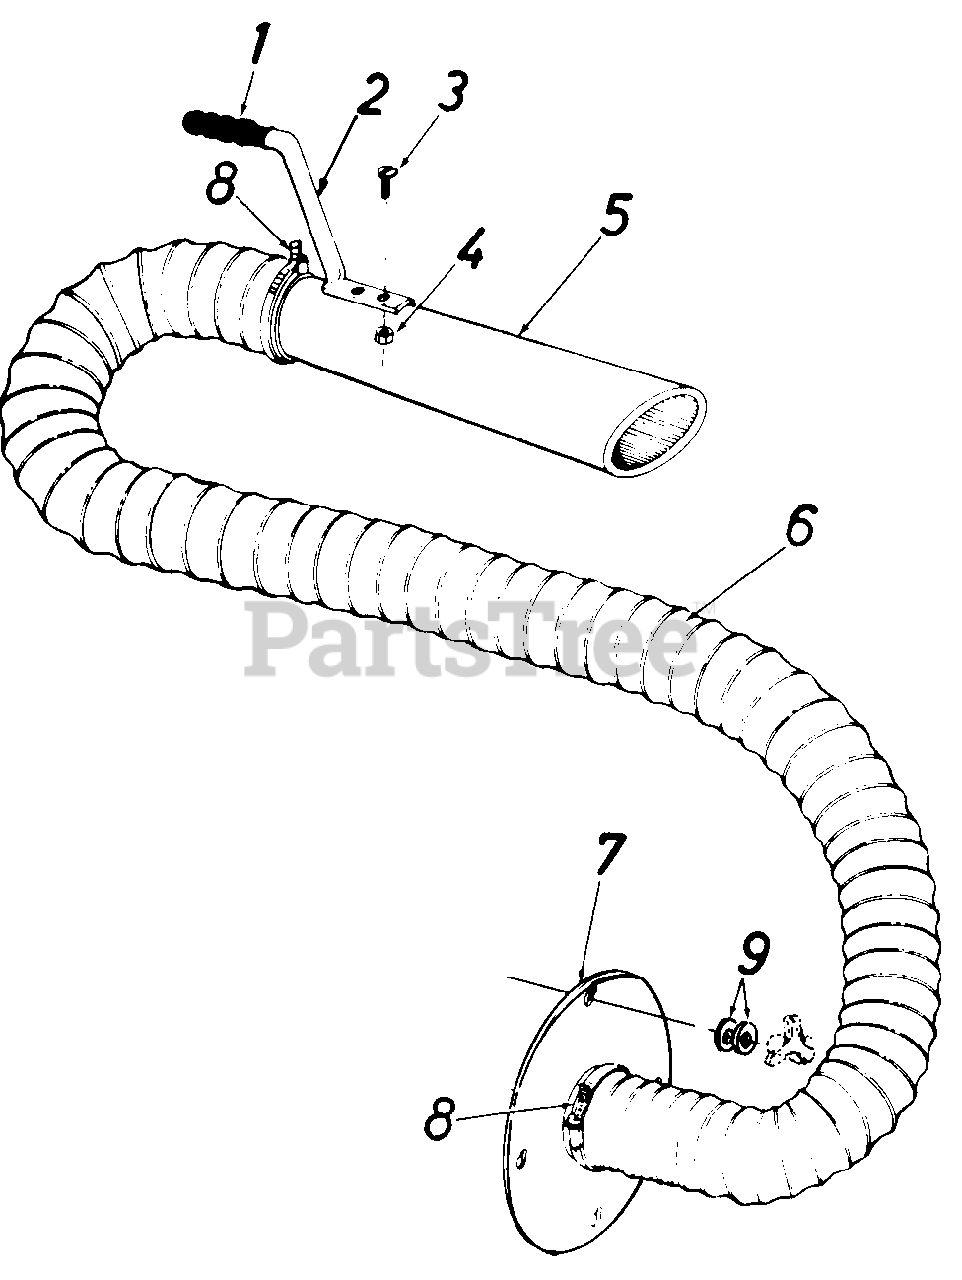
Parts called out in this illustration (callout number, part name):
1	Handle Grip
2	Handle
3	Truss Sems Scr. 10-24 x 1/2" Lg.*
4	Hex Nut 10-24 Thd.*
5	Hose Nozzle
6	Flexible Hose 4" Dia. x 10" Lg.
9	Flat Washer .34 I.D. x 1.12 O.D.
